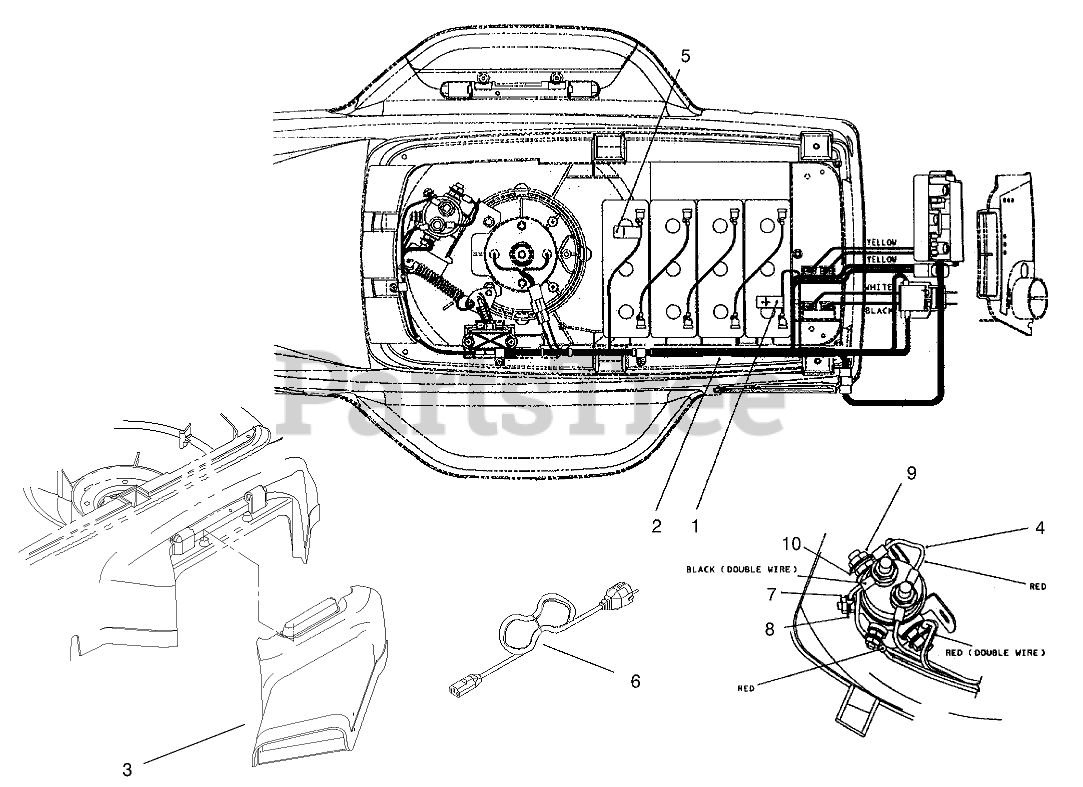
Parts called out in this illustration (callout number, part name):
1	DECAL - POSITIVE
2	HARNESS - WIRE
3	DISCHARGE CHUTE ASM
4	HARNESS-WIRE JUMPER
5	DECAL - NEGATIVE
6	CORD - POWER
7	NUT-HJ
8	WASHER-LOCK
9	NUT-JAM
10	WASHER-LOCK
